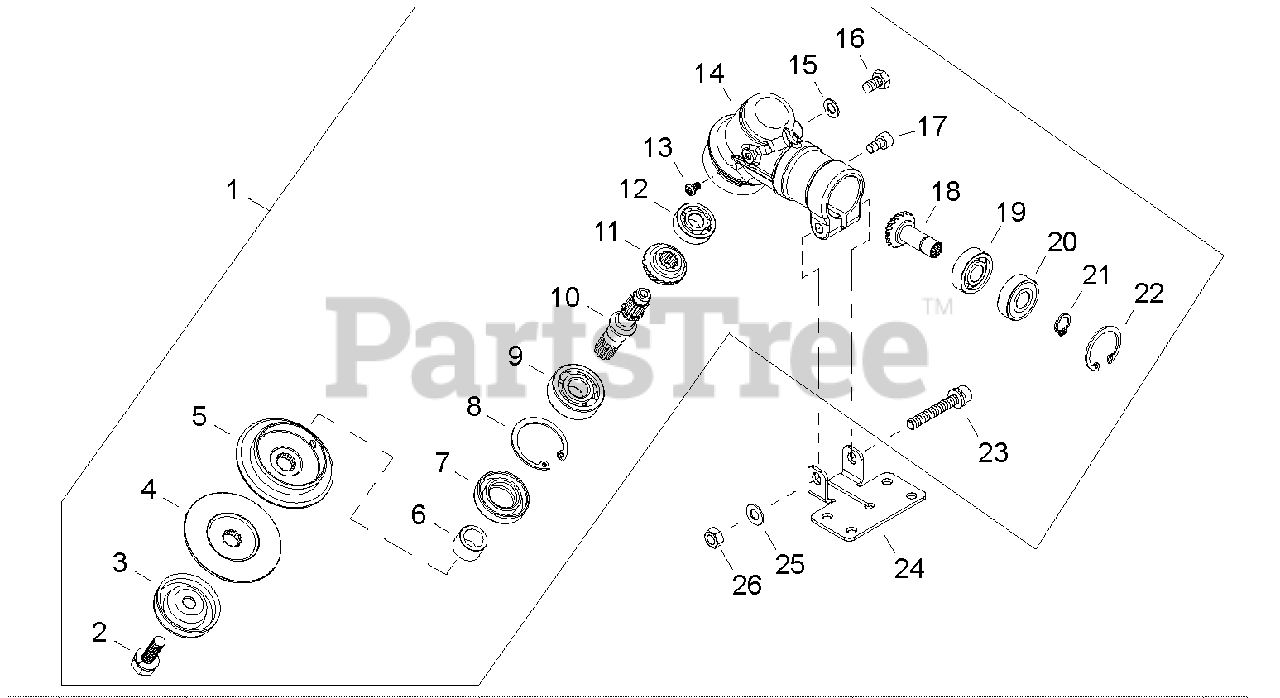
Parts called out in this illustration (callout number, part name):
1	GEAR CASE ASSY
2	SCREW - 8X22
3	GUARD
4	ADAPTOR, BLADE - LOWER
5	ADAPTOR, BLADE - UPPER
6	COLLAR
7	SEAL, OIL
8	RING, RETAINING - 32
9	BEARING, BALL - 6201
10	GEAR - SHAFT
11	GEAR - BEVEL
12	BEARING, BALL - 609
13	SCREW - 4X6
14	CASE, GEAR
15	WASHER - 6
16	BOLT - 6X10
17	SCREW - 5X10
18	GEAR - BEVEL
19	BEARING, BALL - 6000
20	BEARING, BALL - 6000Z
21	RING, RETAINING - 10
22	RING, RETAINING - 26
23	SCREW - 6X40
24	MOUNTING PLATE, SHIELD
25	WASHER - 6
26	NUT - 6
